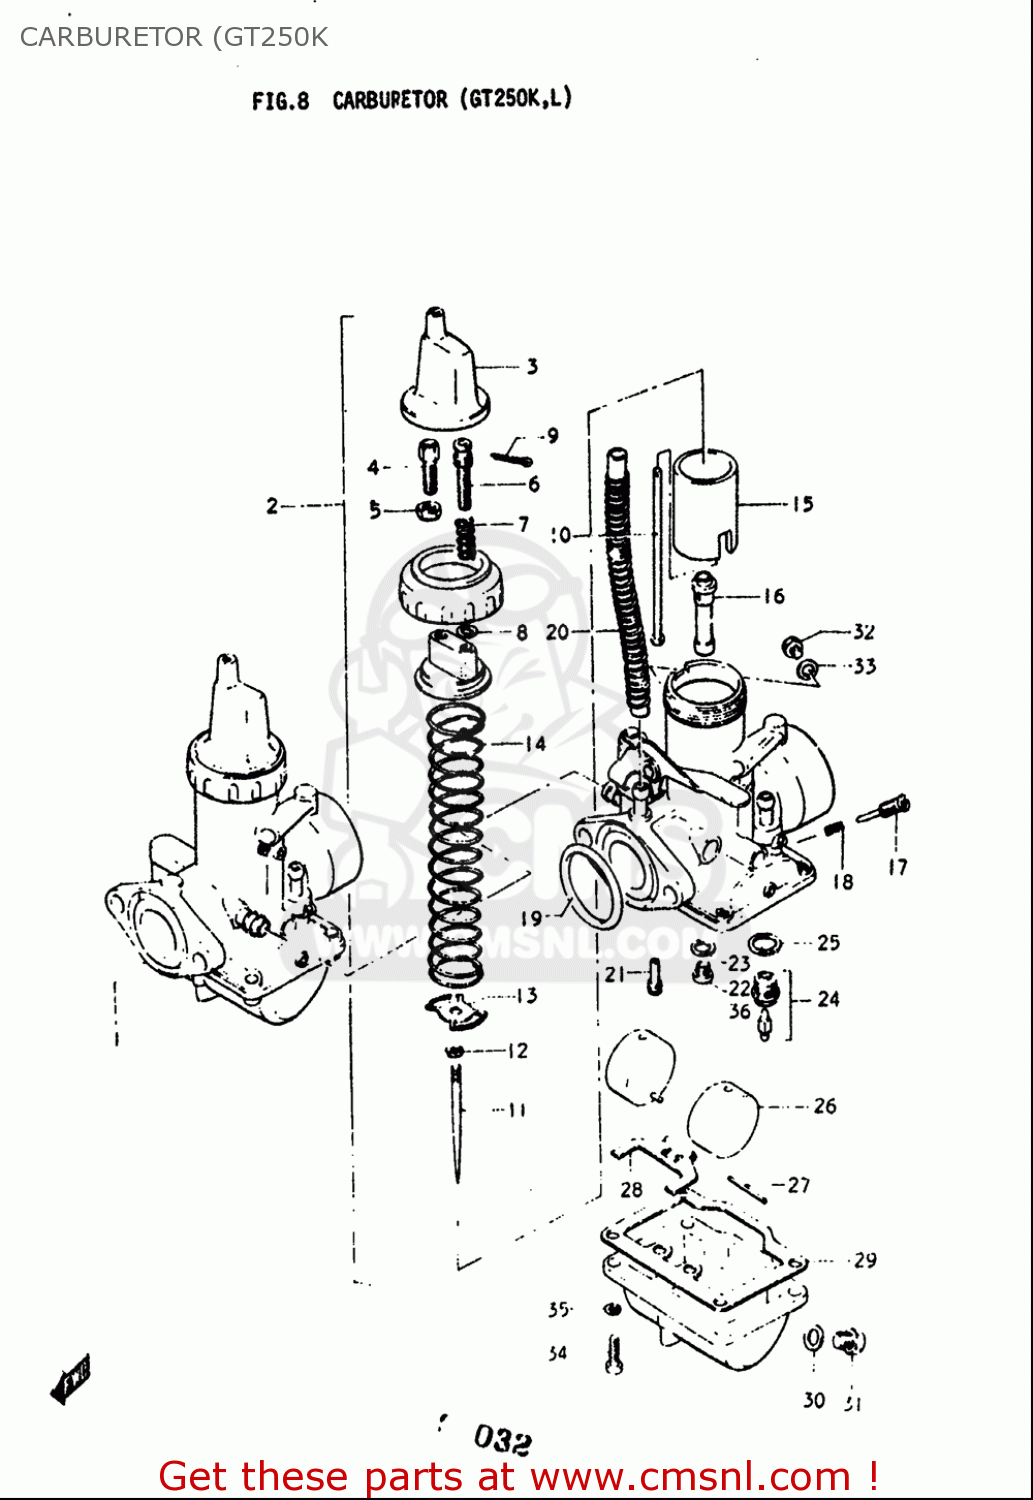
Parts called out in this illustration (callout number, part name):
4	ADJUSTER,CABLE
5	NUT
6	SCREW,THROTTLE VALVE ADJUST
7	SPRING,THROTTLE SCREW
8	LOCK WASHER
9	PIN 12X10
11	NEEDLE,JET(5CN3)
12	CLIP
15	VALVE,THROTTLE
17	SCREW,PILOT AIR
18	SPRING
20	HOSE(4.5X8.5X600)
21	JET,PILOT(25)
22	JET,MAIN(112.5)
23	WASHER
24	VALVE ASSY,NEEDLE
25	GASKET,VALVE SEAT (NAS)
26	FLOAT
29	GASKET,FLOAT CAHMBER (NAS)
30	GASKET,DRAIN,PLUG (NAS)
31	PLUG
33	GASKET,THRO VALVE INSPECTION (NAS)
34	SCREW 4X16
35	WASHER,LOCK
36	JET,MAIN(110)
